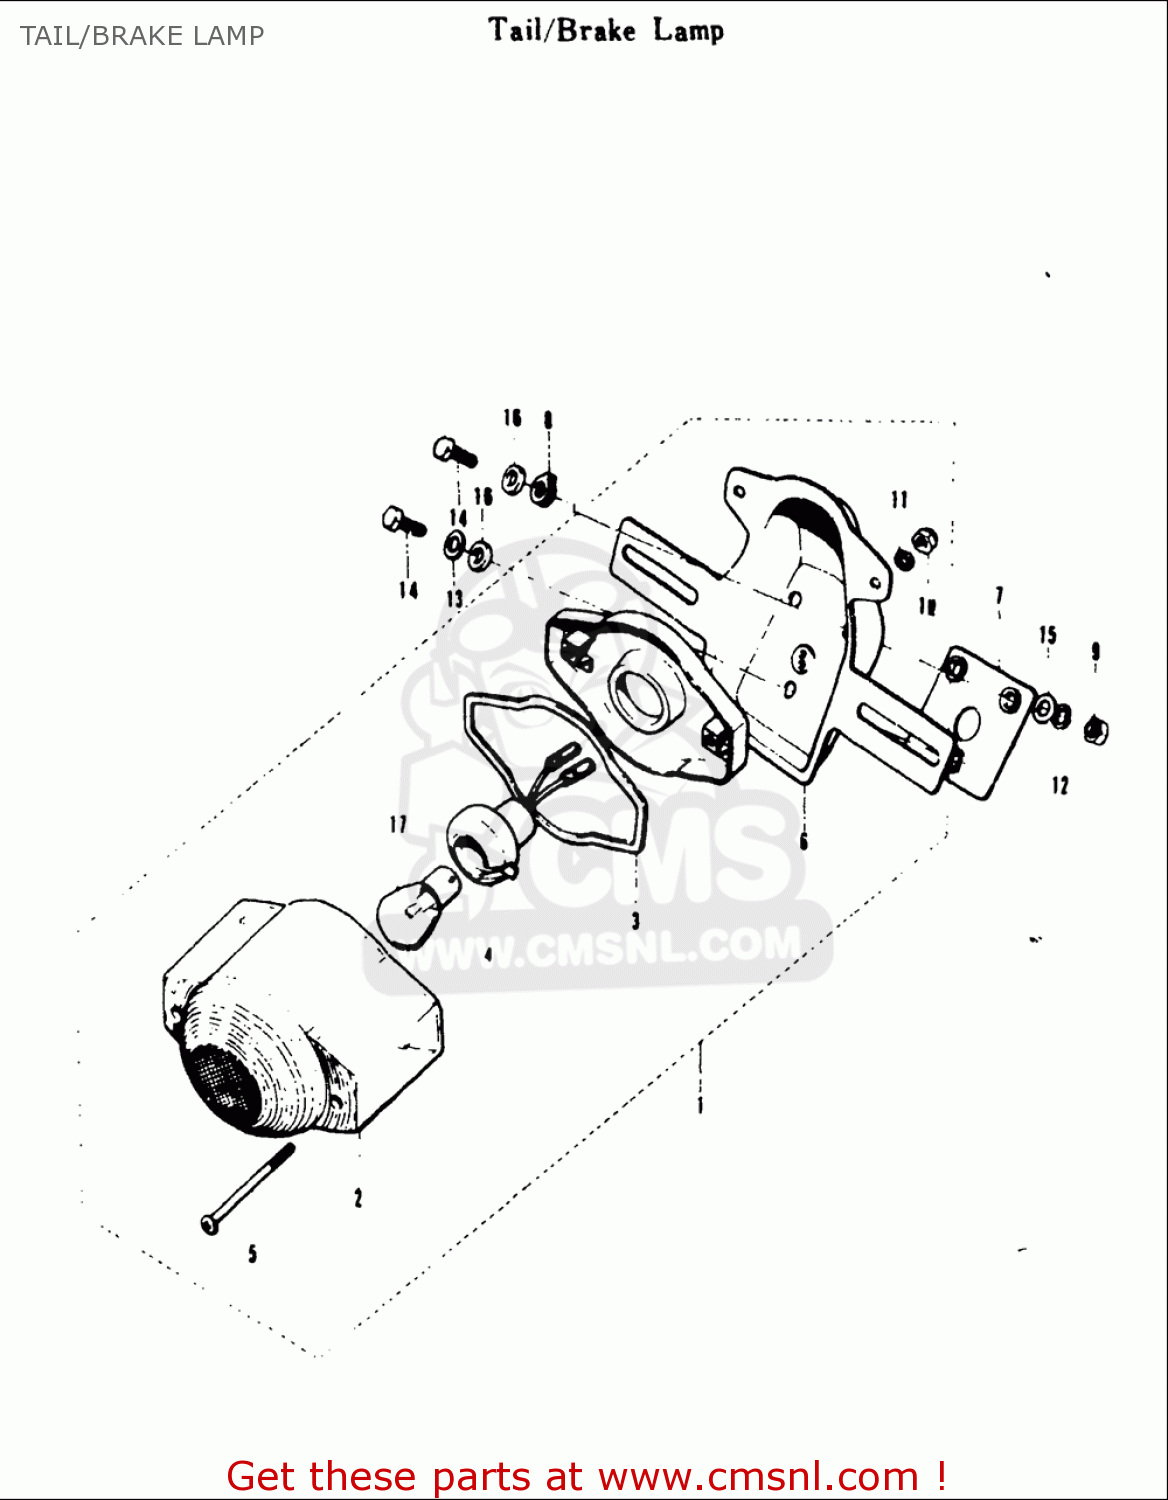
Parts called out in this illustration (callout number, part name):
9	NUT
10	NUT
11	WASHER,LOCK
12	WASHER,LOCK
13	WASHER
14	BOLT(6X71.5)
15	WASHER (6.5X13X1)
17	BULB(12V23W)
